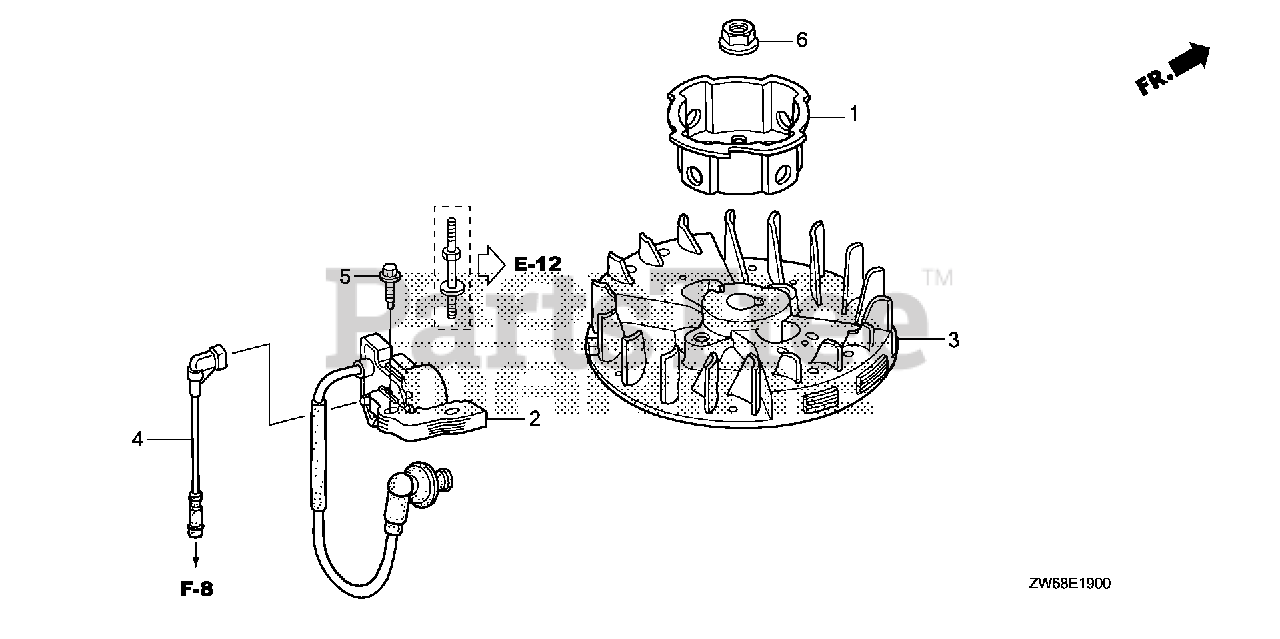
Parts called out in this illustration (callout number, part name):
1	PULLEY, STARTER
2	COIL ASSY., IGNITION
4	WIRE, STOP SWITCH
5	BOLT, FLANGE (5X20) (CT200)
6	NUT, FLANGE (10MM)
